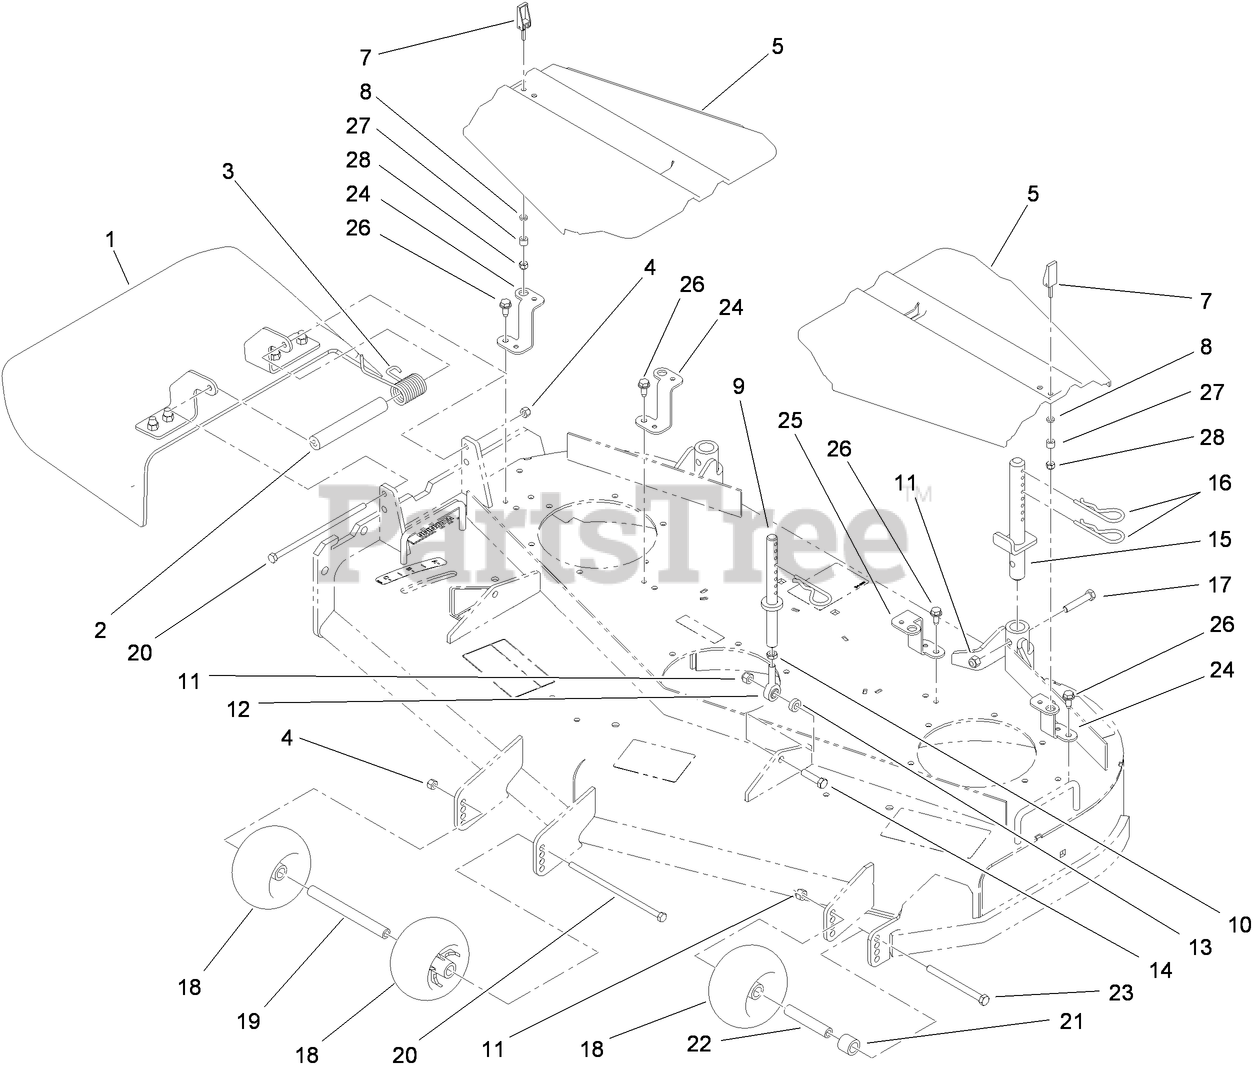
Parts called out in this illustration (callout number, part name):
1	DEFLECTOR ASM
2	SPACER
3	SPRING-TORSION
4	NUT-LOCK, NI
5	COVER-BELT
7	HANDLE-LATCH, SWELL
8	WASHER
9	FRONT PIN ASM
10	NUT-HJ
11	NUT-LOCK, NI
12	BALLJOINT
13	SPACER
14	SCREW-HH
15	REAR PIN ASM
16	PIN-HAIR
17	SCREW-HH
18	ROLLER-SCALP, ANTI
19	SPACER-WHEEL
20	SCREW-HH
21	TUBE-SPACER
22	TUBE-SPANNER
23	SCREW-HH
24	BRACKET-COVER
25	BRACKET-COVER
26	SCREW-HWHTF
27	BUSHING-LATCH, SWELL
28	NUT-LOCK, HH
